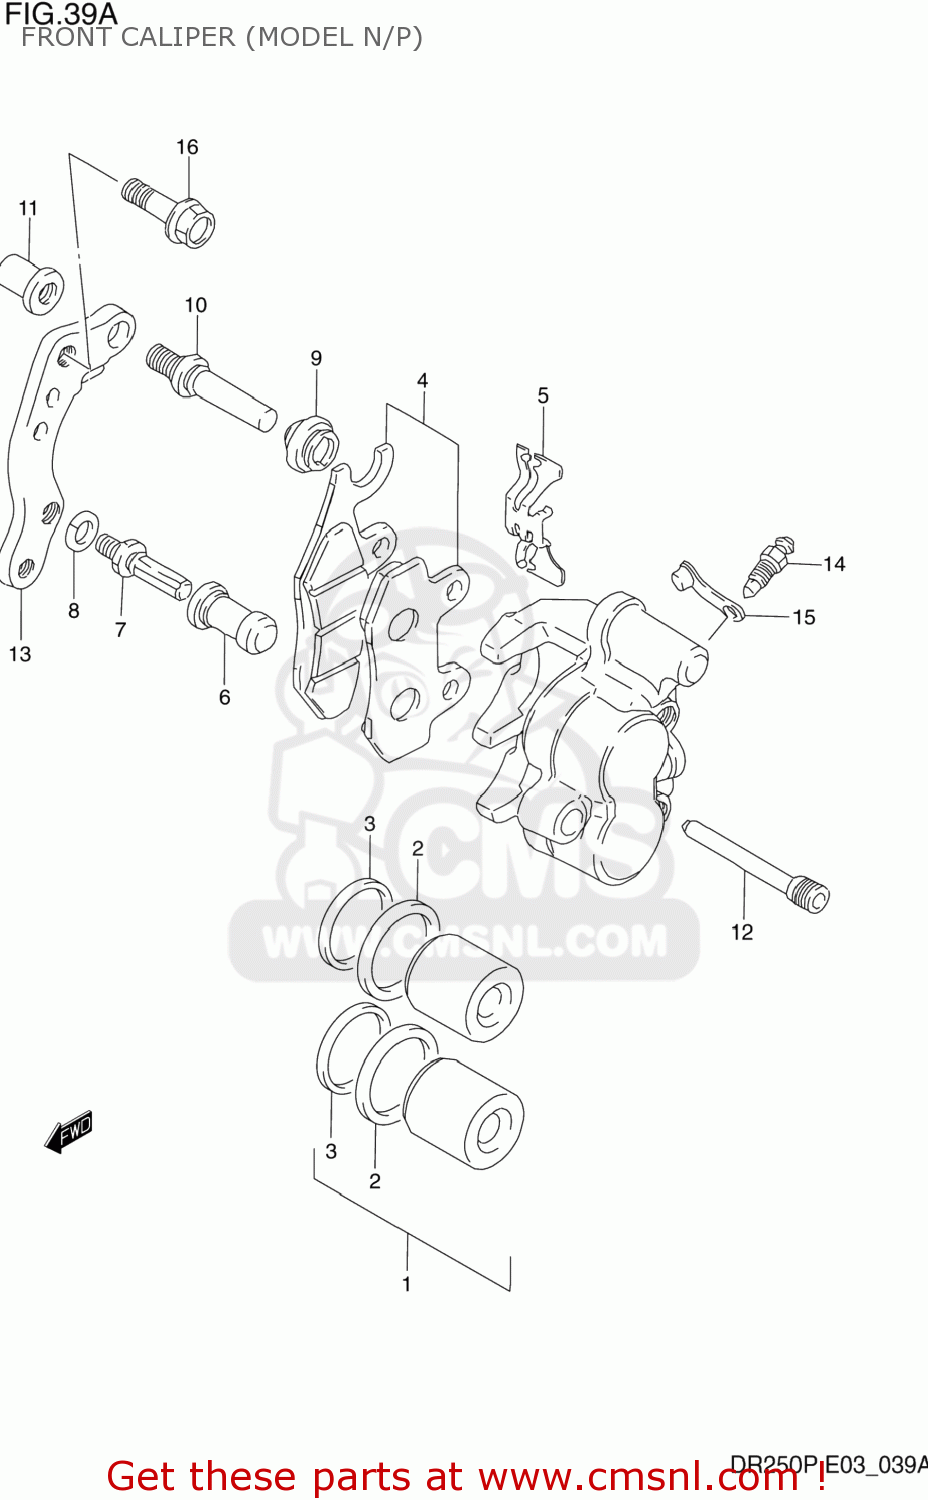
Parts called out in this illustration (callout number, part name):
1	PISTON SET
2	SEAL,PISTON
3	SEAL,DUST
4	PAD SET (NAS)
5	SPRING,PAD
6	BOOT
7	BOLT,PIN
8	WASHER,WAVE
9	BOOT
10	PIN,SLIDE
11	NUT
12	PIN,HOLDER
13	BRACKET
14	BLEEDER
15	CAP,BLEEDER
16	BOLT(8X24)
